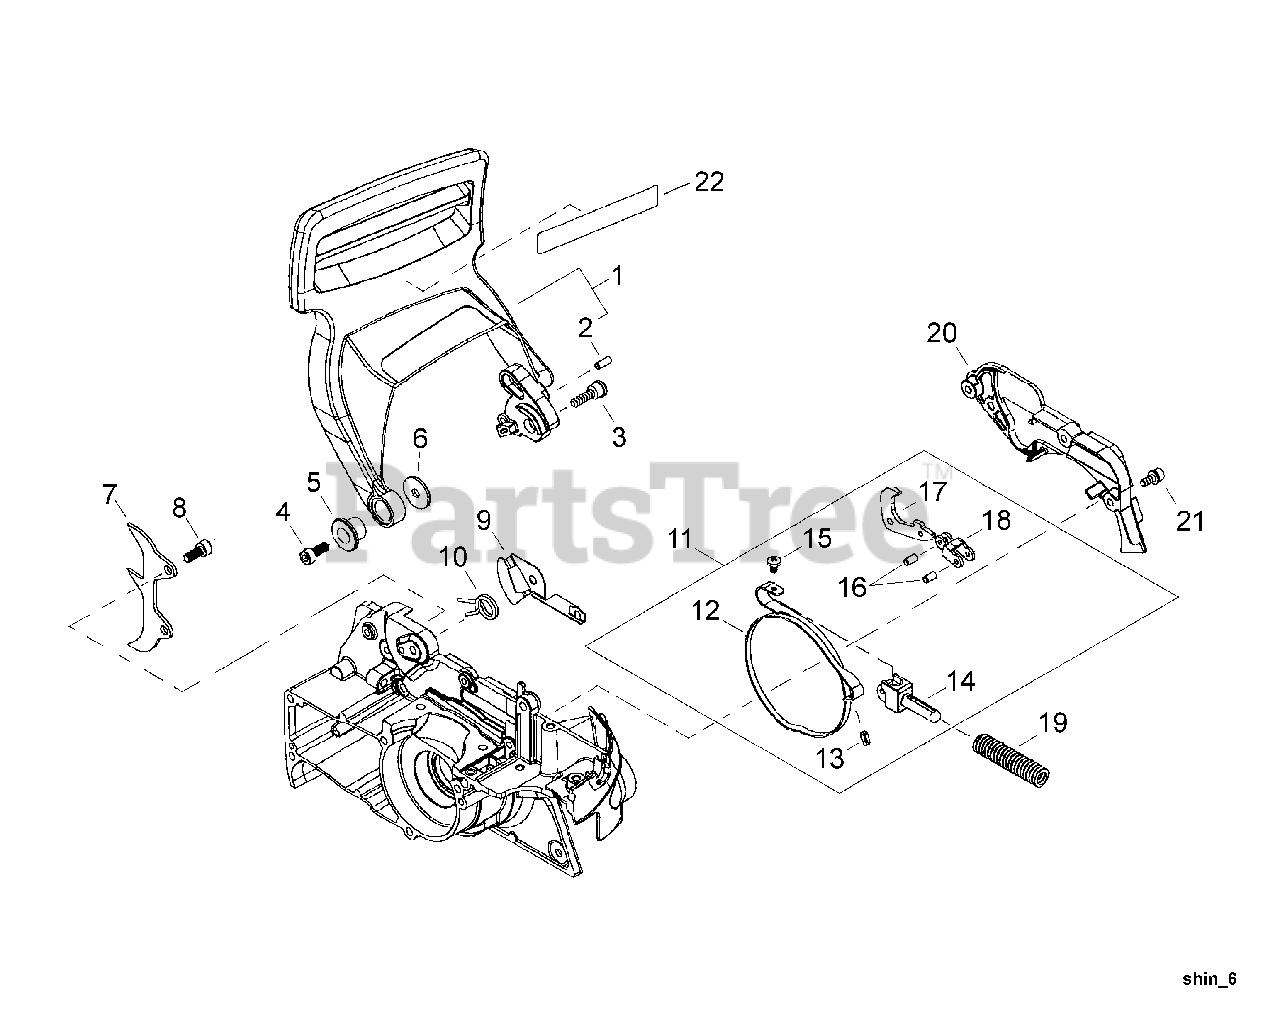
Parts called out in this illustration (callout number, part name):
1	BRAKE ASSY, CHAIN
2	PIN, LOCATING Ø4×8
3	BOLT, ADHESIVE M4×38
4	BOLT M5×18
5	COLLAR, HAND GUARD
6	WASHER 5
7	SPIKE, BUMPER
8	BOLT 5×12
9	PLATE, RETAINING
10	SPRING, TORSION
11	BRAKE ASSY, BAND
12	BAND, BRAKE
13	PIN, SPRING Ø4×10 MM
14	CONNECTOR, BRAKE
15	SCREW, TAPPING M4×10
16	PIN, TIE STRAP Ø3×11.8
17	LEVER, BRAKE
18	STRAP, TIE
19	SPRING, BRAKE
20	COVER, BRAKE
21	BOLT, ADHESIVE M4×10
22	LABEL, CAUTION
